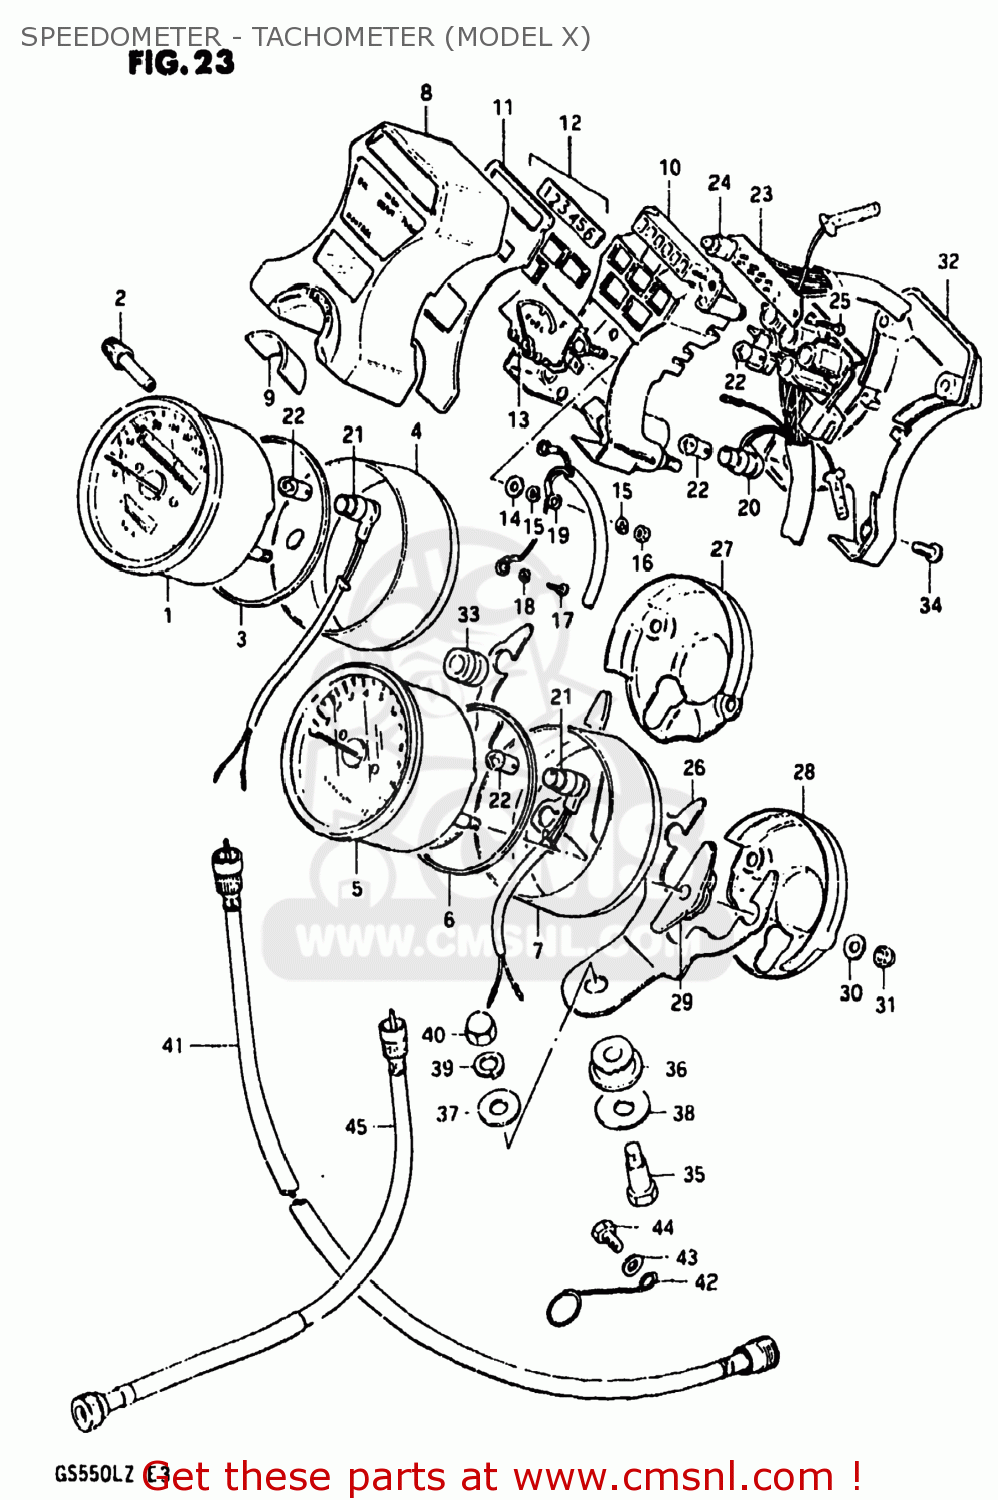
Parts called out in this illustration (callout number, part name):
1	METER,SPEEDOMETER
2	KNOB
3	CUSHION
4	COVER,SPEEDOMETER
5	TACHOMETER
6	CUSHION
7	COVER,TACHOMETER
8	CASE,PILOT BOX,OUTER
9	SEAL,IGNITION SWITCH
10	CASE, PILOT BOX INNER
11	PLATE,PILOT BOX
12	LENS SET,PILOT
13	METER,FUEL
14	WASHER
15	NUT 4MM
16	NUT 4MM
17	SCREW
18	LOCK WASHER
19	LEAD WIRE, FUELMETER
20	SOCKET
21	SOCKET,METER
22	BULB(12V3.4W,T10)
23	INDICATOR ASSEMBLY,GEAR POSITION
24	BULB(14V1.12W)
25	SCREW
26	BRACKET,COMBINATION METER
27	ORNAMENT,SPEEDOMETER
28	COVER,TACHOMETER
29	CUSHION,METER
30	WASHER
31	NUT
32	COVER,PILOT BOX,UNDER
33	CUSHION,PILOT BOX
34	SCREW,PILOT BOX
35	BOLT
36	CUSHION,METER BRACKET
37	WASHER(8.5X23X1.2)
38	WASHER
39	LOCK WASHER
40	NUT
41	CABLE ASSEMBLY,SPEEDOMETER
42	GUIDE,SPEEDOMETER CABLE
43	BOLT, UPPER
44	WASHER
45	CABLE ASSEMBLY,TACHOMETER
